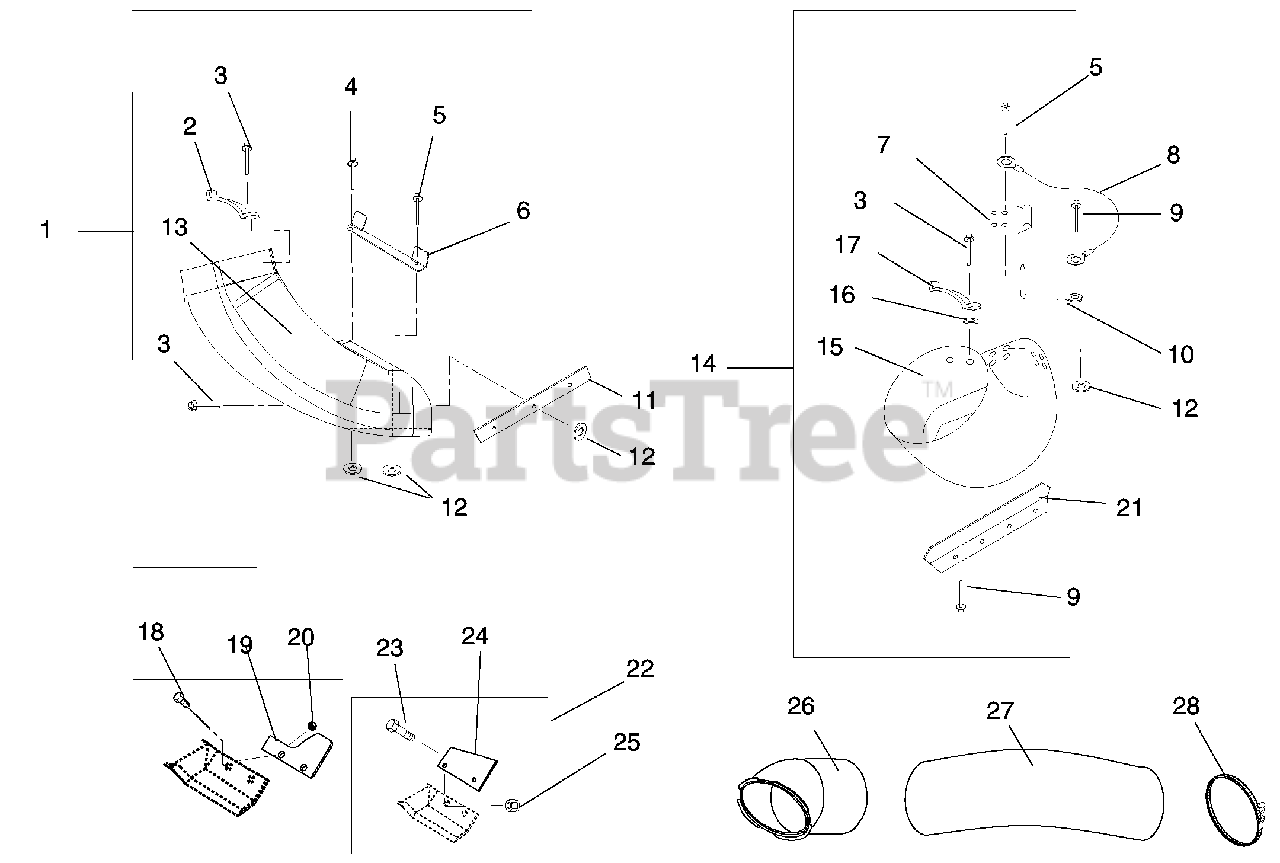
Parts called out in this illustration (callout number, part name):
1	28/32-In. Boot Assembly
2	Tube Retainer
3	Rivet-Pop .187 x .527
4	Rivet-Pop .187 x .277
5	Rivet-Pop .187 x .402
6	Bracket, Bagger Boot Mount
7	Boot Bracket
8	Lanyard
9	Rivet-Tubular .187 x .375 Steel-Aluminum
10	Pull Pin
11	Skirt, Rubber
12	Washer-Flat-Steel .219 x .50 x .049
13	28/32-In. Boot
14	40-In. Boot Assembly
15	40-In. Boot
16	Washer-Flat-Steel .219 x .50 x .049
17	Tube Retainer Clip
18	Bolt-Hex .31-24 x .75 Grade 8
19	28- and 32-Inch Vane
20	Nut-Center-Lock .31-24
21	Extension-Chute
22	40-In. Service Vane Package
23	Bolt-Hex .31-24 x .75 Grade 8
24	40-In. Vane
25	Nut-Center-Lock .31-24
26	Upper Bagger Boot
27	Tube
28	Hose Clamp
